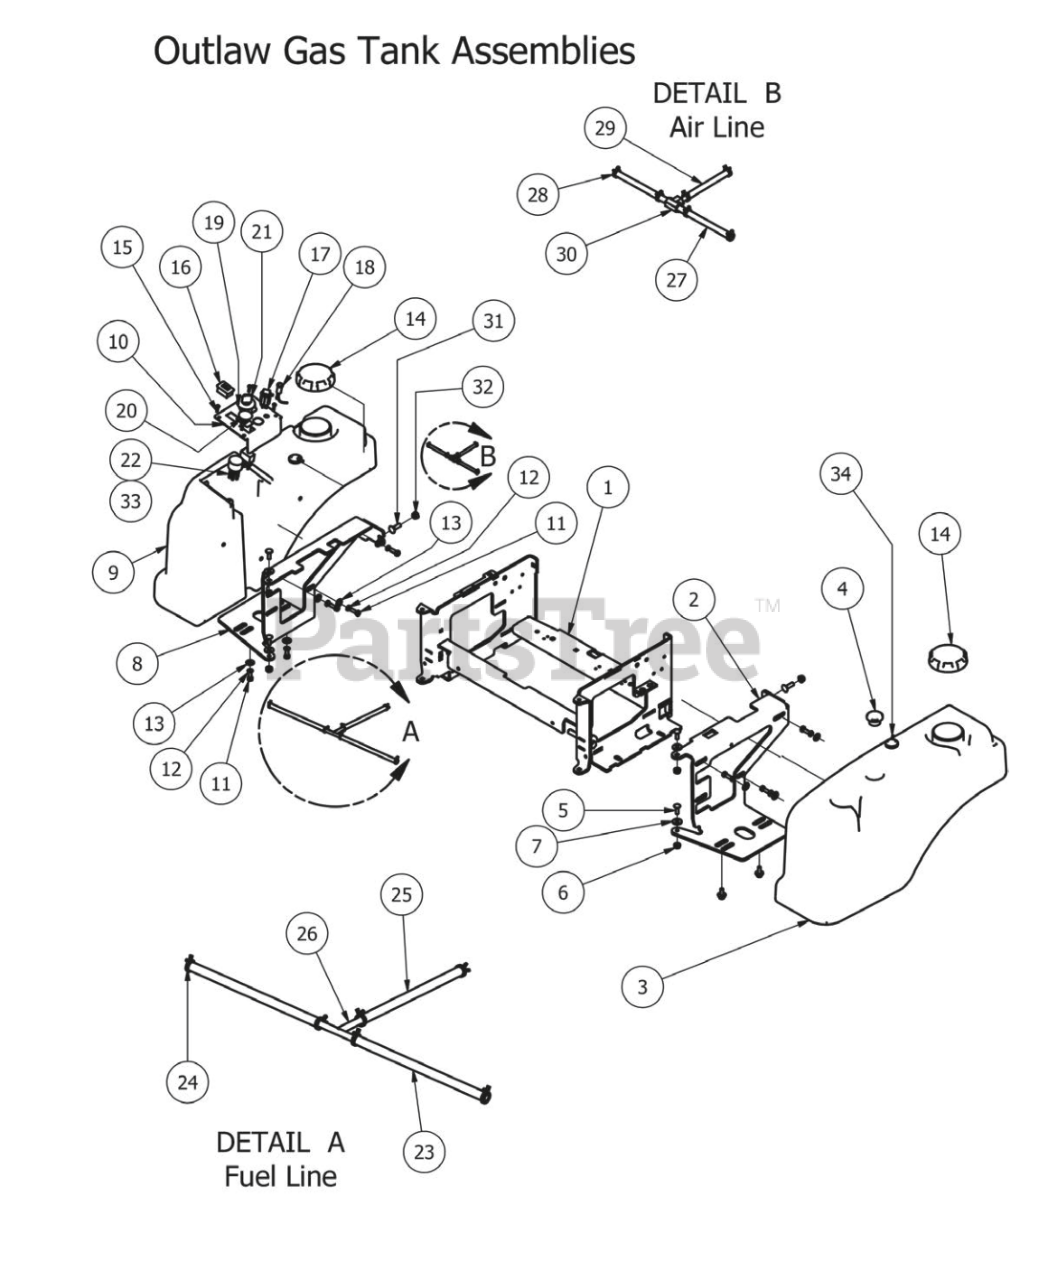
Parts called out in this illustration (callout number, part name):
1	Outlaw Seat Bracket 2012
2	Tank Support 2012 Outlaw (Left)
3	Left Fuel Tank/Outlaw/2012/EPA
4	Fuel Gauge Tanks W/downtube
5	5/16" x 1" Carriage Bolt
6	5/16-18 Nylon Flange Nut
7	.360 ID Plastic Washer
8	Outlaw Tank Support 2012 (Right)
9	Right Fuel Tank/Outlaw/2012/EPA
10	Outlaw Instrument Panel 2010
11	5/16" x 1" Bolt
12	5/16" Lock Washer
13	5/16" Flat Washer
14	3.5" Tethered Fuel Cap
15	10-32 x 3/8" Button Socket Head Bolt
16	Tachometer
17	12V AUX Connection
19	Ignition Switch
20	PTO Engager
21	Ignition Key
22	Wiring Harness-23hp Briggs/30hp Briggs Outlaw
23	Fuel Line Assembly
24	1/4 fuel clamp
25	1/4" fuel line hose
26	fuel line T
27	1/4" Vinyl Tubing-Black
28	3/16 vinyl clamp
29	3/16 vinyl tubing
30	Brass fuel line T
31	3/8" x 1 1/4" Carriage Bolt
32	3/8" Nylock Flange Nut
33	Wiring Harness- 30hp Kohler 2006 and up
34	Rollover Valve-White
